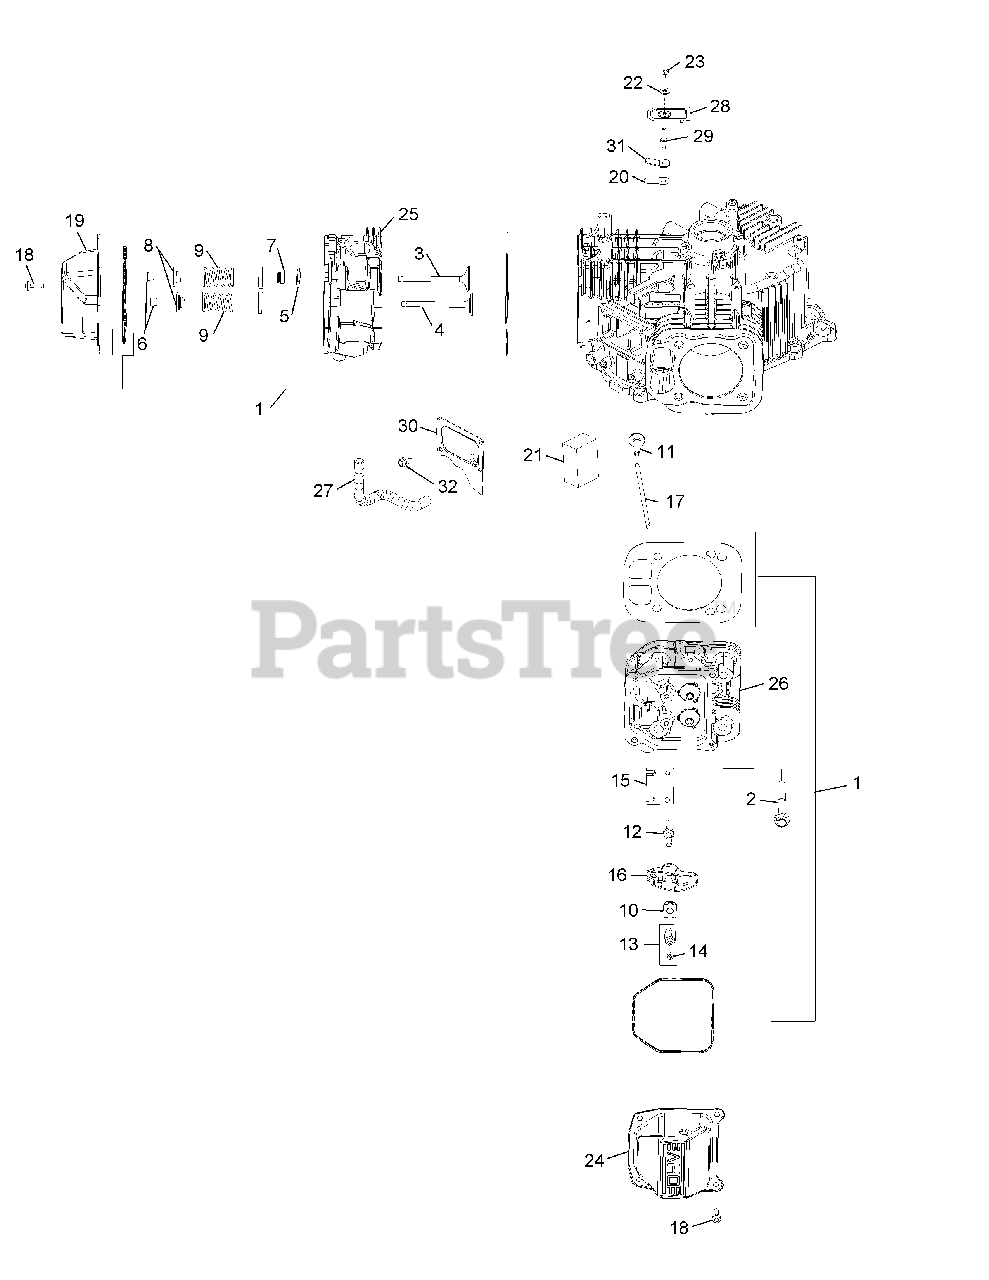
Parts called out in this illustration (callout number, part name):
1	Cylinder Head Gasket Kit
2	Flange Screw, M10 x 1.5 x 90
4	Exhaust Valve
5	Spacer (.010")
6	Retainer Kit
7	Valve Band Seal
8	Valve Spring Cap
9	Valve Spring
10	Rocker Arm Pivot
13	Hex Nut Assembly (Inc. #14)
18	Pan Head Screw
20	Breather Reed
21	Breather Filter
22	Sealing Washer
23	Lock Nut, M5 x 8
24	Rocker Cover
25	Cylinder Head Assembly Kit, #1
26	Cylinder Head Assembly Kit, #2
27	Breather Hose
28	Breather Cover
30	Breather Media Cover
31	Reed Retainer
32	Thread Forming Screw
